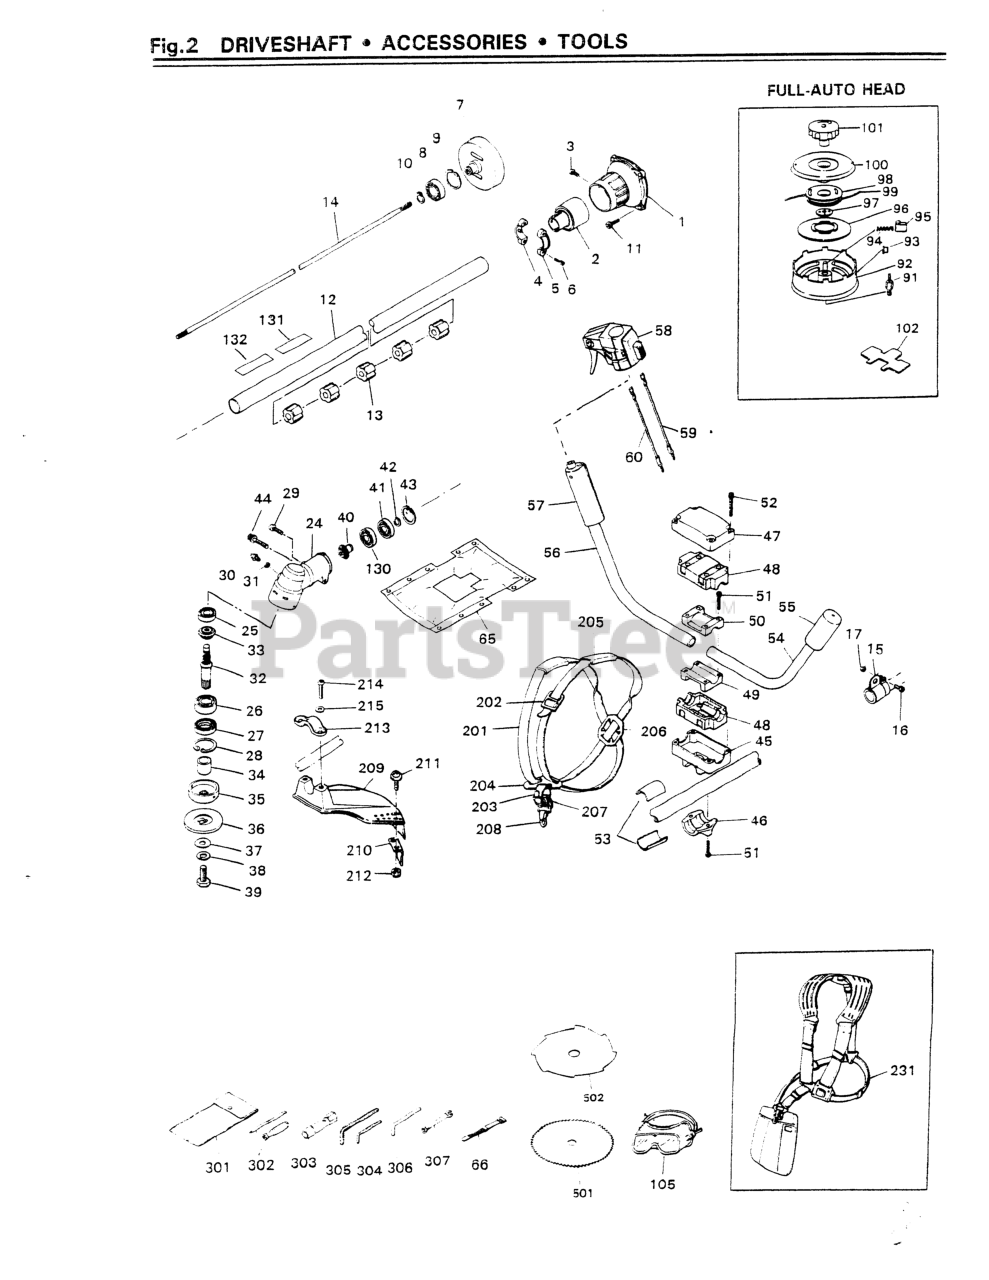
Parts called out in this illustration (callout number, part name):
3	SCREW, M6 x 10
6	BOLT
7	DRUM, SPLINED
8	BEARING
9	RING, SNAP, M15 X 1.0
10	RING, SNAP, M35 X 1.5
12	PIPE (USE -12101)
13	BUSHING (RPLS -11320)
15	HANGER COMP (USE 9366-17100)
16	BOLT, M6 x 16
17	NUT, M6 X 5
25	BEARING (RPLS T3403-13510)
28	RING, SNAP, M35 X 1.5
29	BOLT, M5 X 10
30	FITTING, GREASE
31	WASHER, M6 X .8
33	GEAR (NLA)
36	HOLDER (B)
37	WASHER, M10 x 3.2
38	WASHER
39	BOLT (REPLACES 3130-13260)
42	RING, SNAP
44	BOLT, M6 x 1.35
46	CAP, LOWER
47	CAP, UPPER
48	ABSORBER
49	CLAMP (A)
50	CLAMP (B)
51	BOLT, M5 X 25
52	BOLT, M5 X 30
54	HANDLE COMPL, LEFT
56	HANDLE COMPL, RIGHT
57	GRIP
58	LEVER ASSEMBLY
59	CORD A (RED)
60	CORD (RPLS -14720)
66	BAND
91	ADAPTER (NO LONGER AVAIL)
92	HOUSING, SPOOL
93	EYELET (RPLS -15220)
94	SPRING, WHITE
94	SPRING, RED
94	SPRING, SILVER
94	SPRING, CAM
95	SLIDE CAM (1 PC)
96	CAM DISK
97	NUT, FLAT
102	FASTENING TOOL
130	BEARING (RPLS T3403-13510)
131	PLATE, NAME
210	BLADE
211	SCREW, M5 x 12
212	NUT
213	CLAMP
214	BOLT, M6 x 1.30
215	WASHER, M6 X 15
231	HARNESS ASSEMBLY
302	SCREWDRIVER
304	WRENCH (TOOL)
305	WRENCH (TOOL)
306	BAR
307	SPANNER, 8 X 10 (RPLS 2540- )
501	BLADE, CIRCULAR SAW
502	BLADE, EDDY SAW
